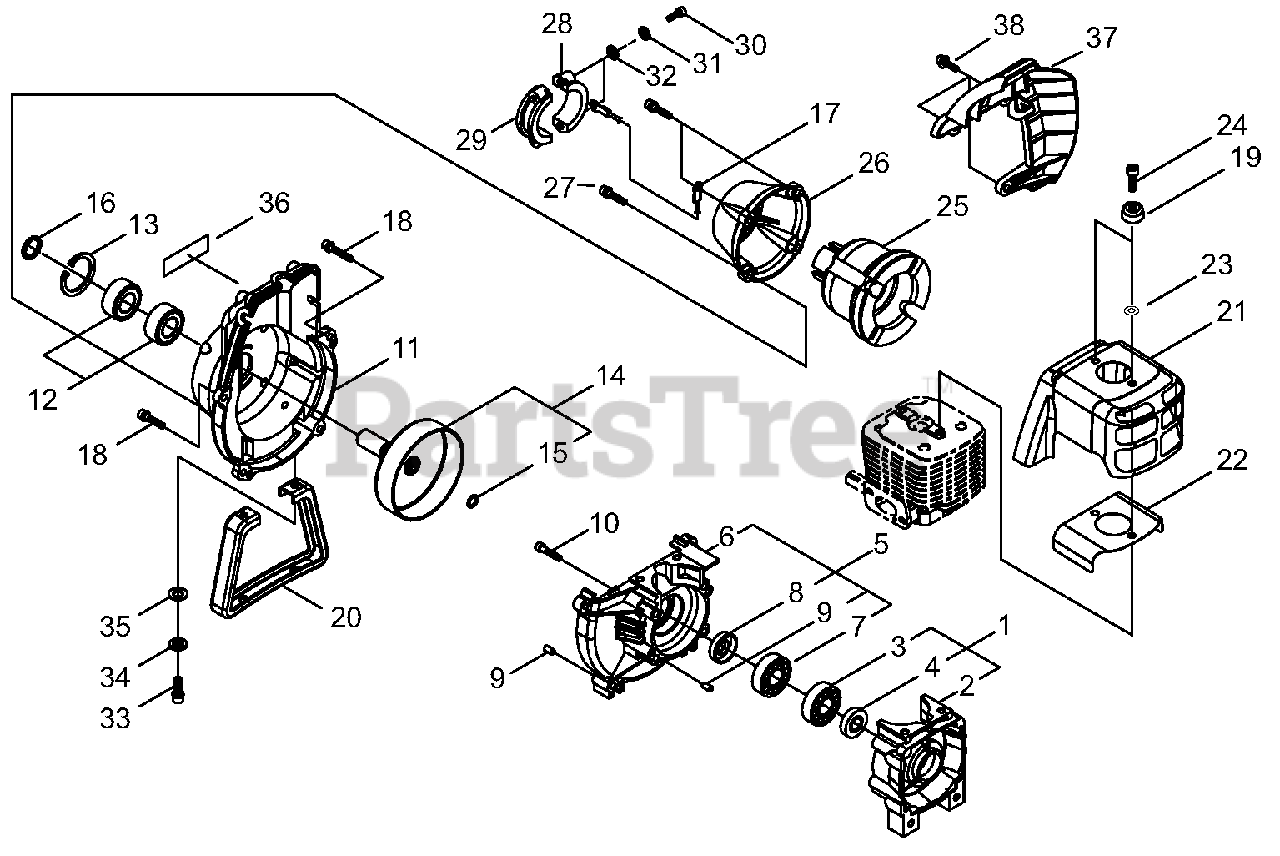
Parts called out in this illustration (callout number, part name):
1	CRANKCASE KIT - REAR
2	CRANKCASE - REAR
3	BEARING, BALL - 6202C3
4	SEAL, OIL - 15
5	CRANKCASE KIT - FRONT
6	CRANKCASE - FRONT
7	BEARING, BALL - 6202C3
8	SEAL, OIL - 15
9	PIN - LOCATING
10	SCREW - 5X30
11	CASE, FAN
12	BEARING, BALL - 6002
13	RING, RETAINING - 32
14	CLUTCH DRUM KIT
15	RING, RETAINING - 11
16	RING, RETAINING
17	LEAD - GROUND
18	SCREW - 5X20
19	COVER
20	GUARD, FUEL TANK
21	COVER, ENGINE
22	SHIELD, CYLINDER
23	WASHER
24	SCREW - 5X14
25	CUSHION
26	CONNECTOR, CAP
27	SCREW - 5X20
28	CLAMP - B
29	CLAMP - A
30	SCREW - 5X25
31	LOCKWASHER - 5
32	WASHER - 5
33	SCREW - 5X20
34	LOCKWASHER - 5
35	WASHER - 5
36	LABEL - MODEL
37	PROTECTOR ASSY
38	SCREW - 4X16
